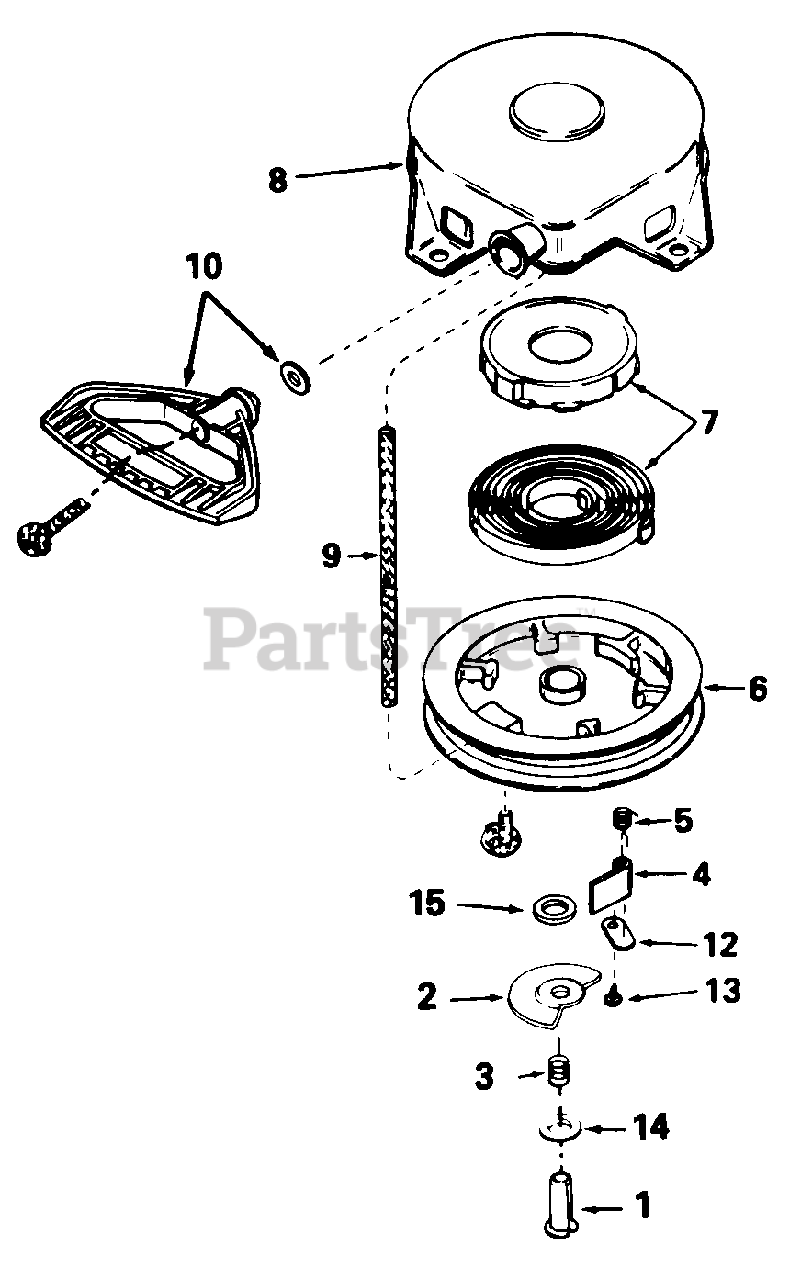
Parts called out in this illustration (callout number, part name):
1	Pin, Spring
2	Cam, Dog
3	Spring, Brake
4	Dog, Starter
5	Spring, Dog
7	Spring & Keeper Ass'y.
8	Housing, Starter
9	Rope, Starter
10	Handle, Mitten Grip
12	Retainer, Dog
13	Screw, No. 6 x 5/16
